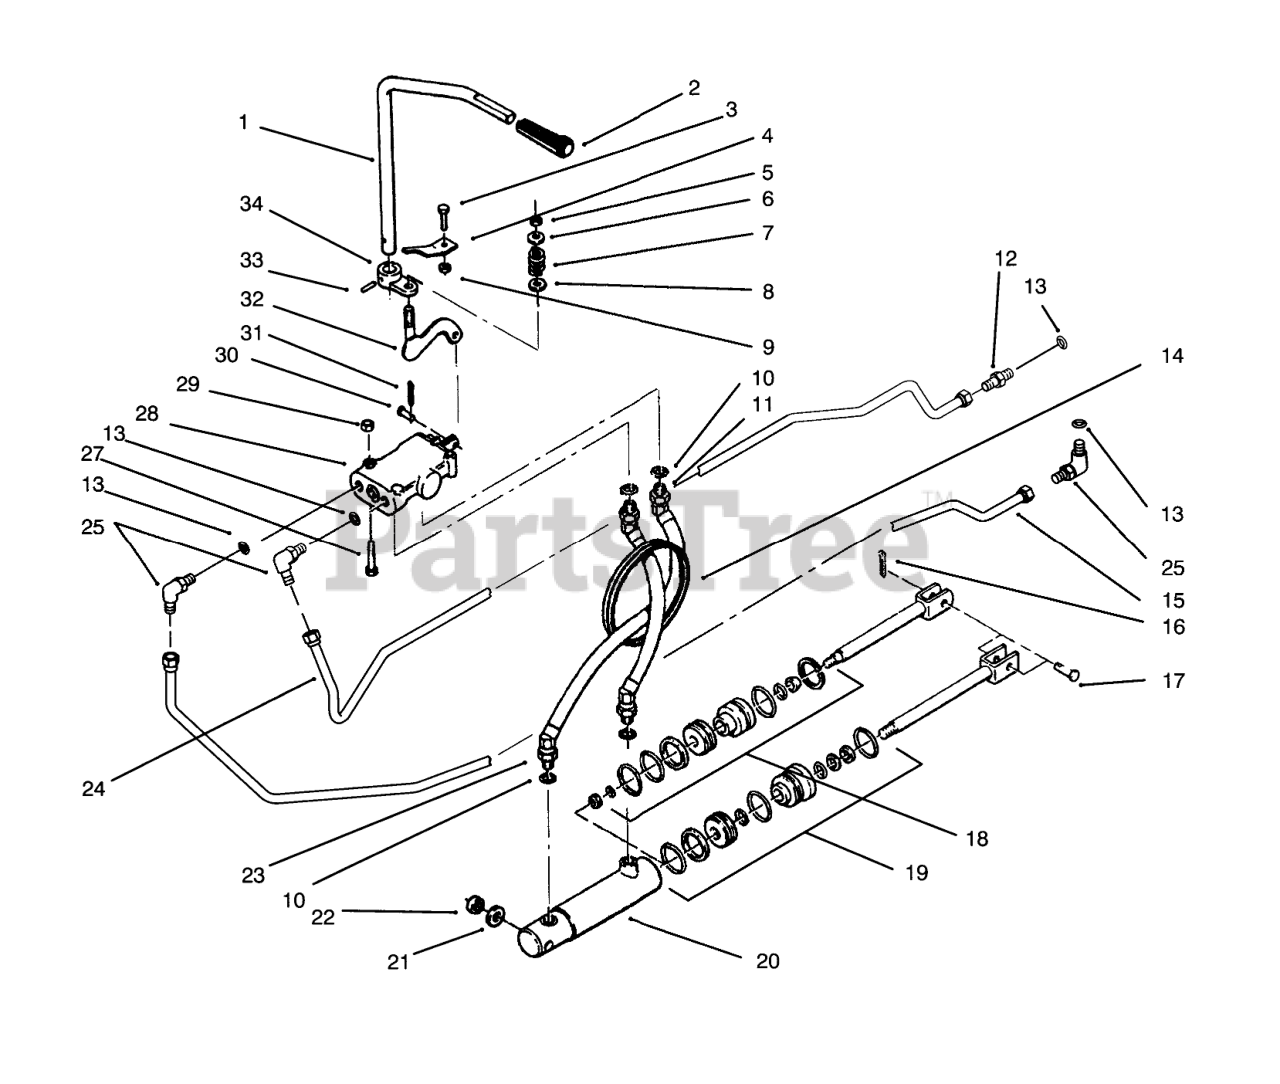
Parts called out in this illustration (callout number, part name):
1	ROD-LIFT CONTROL
2	KNOB-HYDRAULIC LIFT
3	SCREW-HH
4	BRACKET-CONTROL R B
5	NUT-LOCK, NI
7	SPRING
8	SCREW-HH
9	NUT-LOCK, NI
10	O RING
11	Hose ASM-Hydraulic
12	Fitting-Straight (Incl. Ref. #13)
13	0-Ring
14	GROMMET
15	TUBE-HYD PRESSURE
16	PIN-COTTER
17	Pin-Clevis
18	S/A O-RING&GASKET AS
19	S/A 108872 HYD CYL
20	Cylinder-Hydraulic (Incl. Ref. #18-19)
21	SPACER
22	WASHER
23	Hose ASM-Hydraulic
24	TUBE-HYD RETURN
25	ELBOW
27	SCREW-HH
28	Valve-Hydraulic (Incl. Ref. #30-31)
29	NUT-LOCK, NI
30	PIN-CLEVIS
31	Pin-Cotter
32	WLDMT-LIFT BAR
33	SPIROL PIN 7/32X7/8
34	ARM-CONTROL
